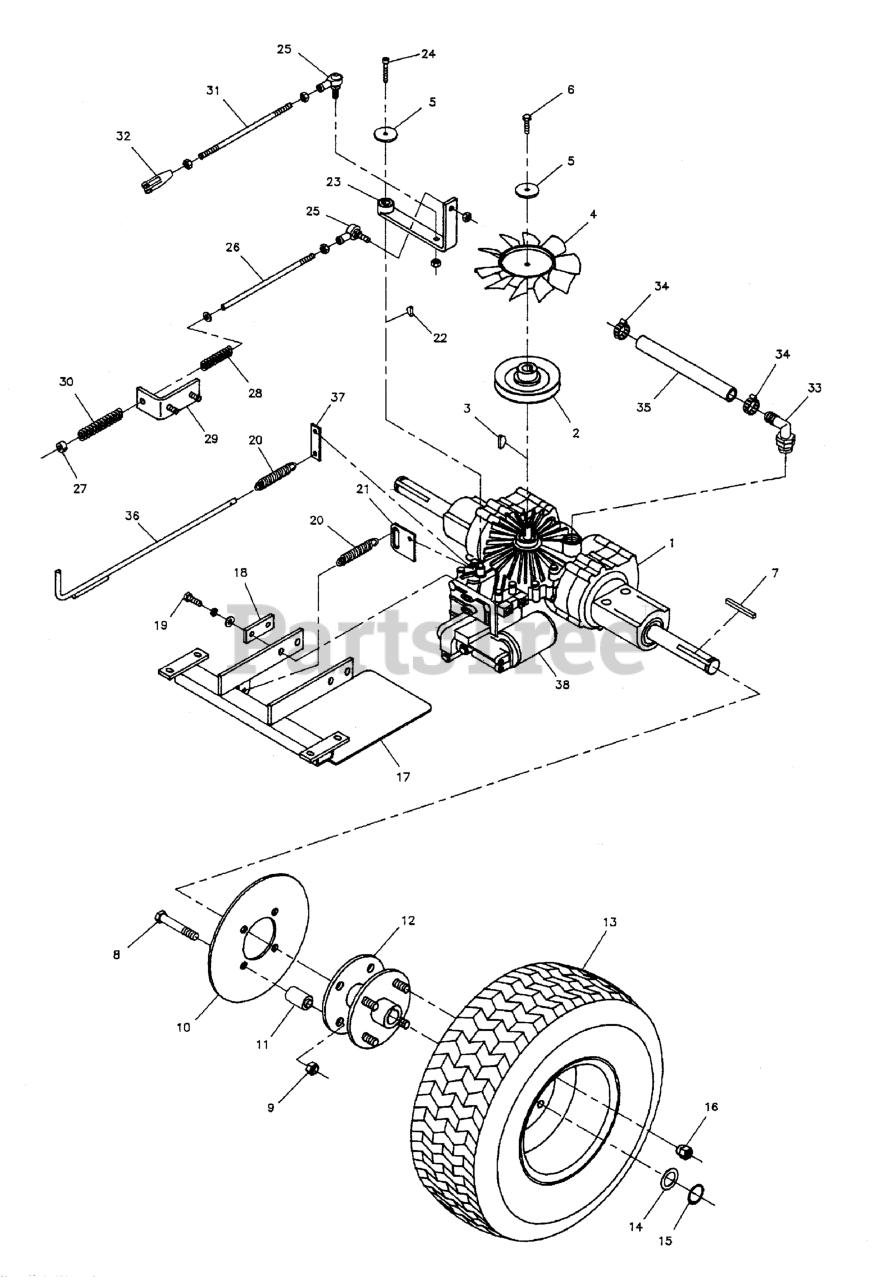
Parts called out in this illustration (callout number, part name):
1	TRANSAXLE (model 751)
2	TRANSMISSION INPUT PULLEY
3	KEY, #61 Woodruff
5	WASHER, .265 x 1.50 x .109
6	BOLT, Loctite Patch, 1/4-20 x 3/4
7	KEY, 1/4 SQ. X 2-1/2
8	BOLT, 1/2-20 x 3
9	NUT, Hex, Nylon Lock, 1/2-20
10	BRAKE DISC
11	BRAKE DISC SPACER
12	DRIVE HUB
13	WHEEL & TIRE ASSEMBLY, 18 x 7.50 x 8
13	TIRE ASSM, 16 x 6.50 x 8
15	RING, Retaining
16	LUG NUT, 1/2-20
17	Transmission Brace
17	TRANSMISSION BRACE
18	BRACE, Hydro Spacer
19	BOLT, 5/16-18 X 1 GD5 YZ
20	SPRING, Extension
21	DUMP VALVE LEVER
22	KEY, #3 Woodruff
23	CONTROL ARM
24	BOLT, Allen Head, 1/4-20 x 1-1/2
25	BALL JOINT 5/16-24 LH FEMALE W/STUD, BR
26	ROD, Neutral
27	COLLAR, 5/16" Set
28	SPRING, Compression
29	NEUTRAL BRACKET
30	SPRING, Compression
31	ROD, Control
32	CLEVIS, 5/16-24, Plastic
33	90 Degree Fitting
34	CLAMP, #10 Hose
35	Hose, 8-1/4"
36	DUMP VALVE ROD
37	DUMP VALVE EXTENSION
38	FILTER, Transmission Oil
